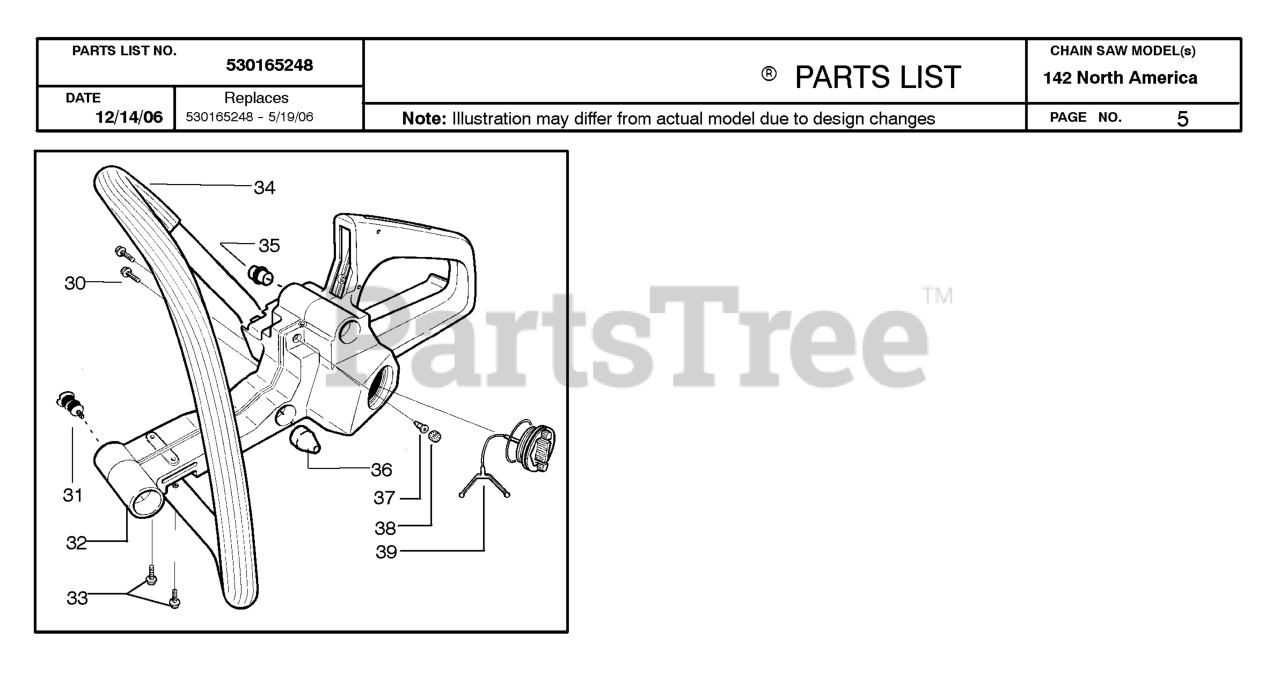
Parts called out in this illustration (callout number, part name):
32	TANK HANDLE ASSY
34	HANDLE FRONT
35	FRONT HANDLE ISOLATOR
36	SHOCK MOUNT(X2) 36/41
37	VALVE-CHECK (DUCKBILL)
38	BRONZE PLUG
39	FUEL CAP KIT
